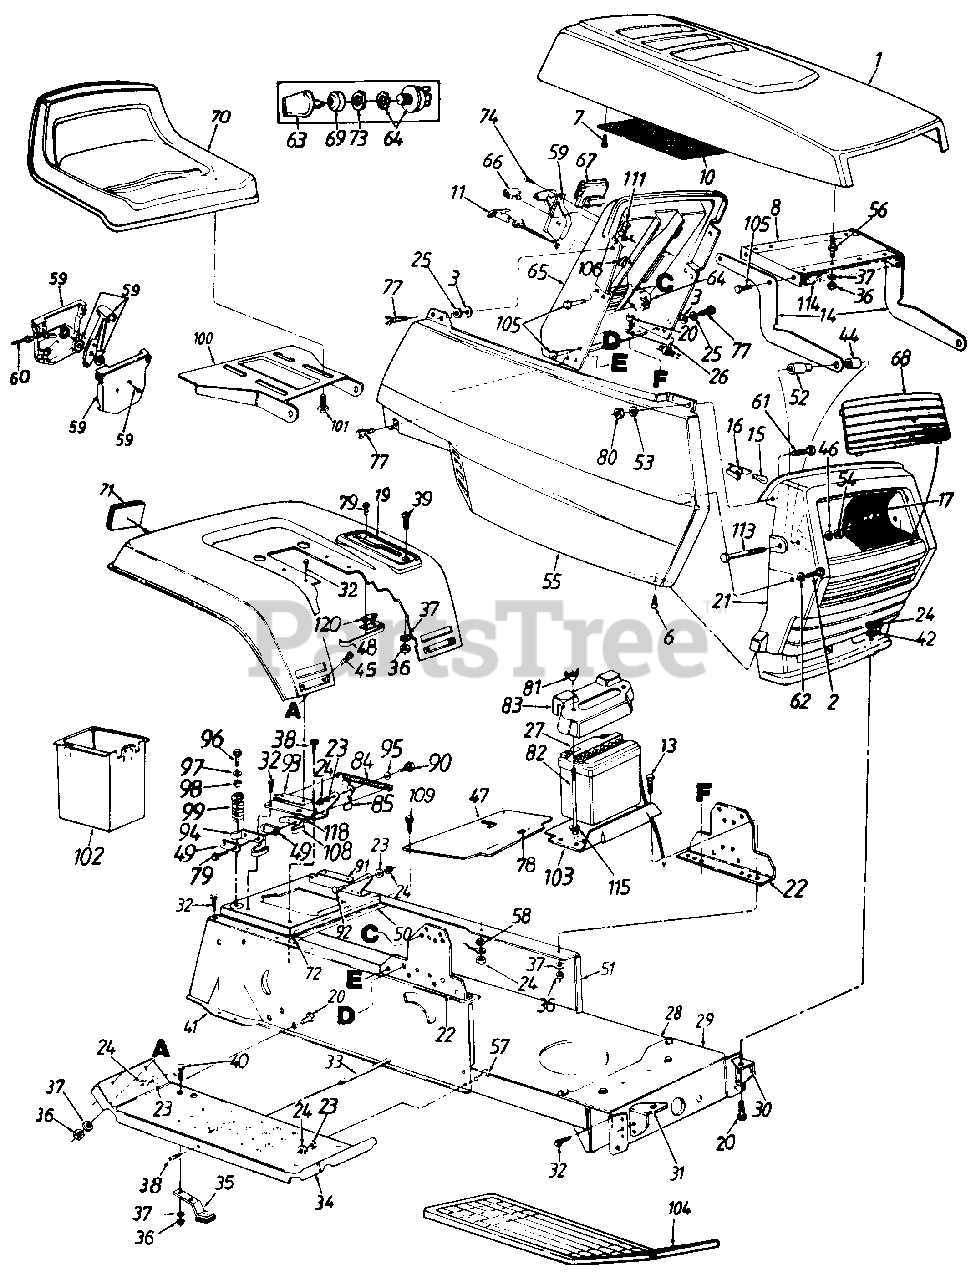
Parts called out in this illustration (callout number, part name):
3	Bolt Retainer 1/4" I.D.
6	Truss Mach. AB-Tap Scr. #10 x .5" Lg.
7	Hex Wash Hd. AB-Tap Scr. #8 x .5" Lg.
8	Hood Plate
11	Choke Control 38" Lg.
13	Hex Bolt 1/4-20 x .62" Lg.
14	Hood Hinge
15	Lamp
16	Twist Lock-Lamp Socket
17	Refiector-Headlight
19	Speed Control Index Brkt.
20	Hex Bolt 5/16-18 x .75 Lg.
21	Grille
22	Dash Support Bracket
23	L-Wash. 5/16" l.D.
24	Hex Nut 5/16-18 Thd.
25	Fl-Wash. 1/4" I.D. x .93" O.D.
26	Cable Tie
27	12 Volt Battery
28	Lower Frame
29	Front Pivot Brk't.
30	Grille Mount Brk't.-L.H.
31	Grille Mount Brk't.-R.H.
32	Hex Wash. Hd. AB-Tap Scr. 5/16 x .75 Lg.
33	Running Board Rod
34	Running Board
35	Blade Brake Ass'y.
36	Hex Nut 1/4-20 Thd.
37	L-Wash. 1/4" I.D.
38	Truss Mach. Scr. 5/16-18 x .75"
39	Truss Mach. Scr. 1/4-20 x .75
40	Carr. Bolt 1/4-20 x .62"
41	R.H. Side Frame
42	Fl-Wash. .34" l.D. x.68" O.D.
45	Carriage Bolt 1/4-20 x .50" Lg.
46	Fl-Wash. .328" l.D. x .68" O.D.
47	Transmission Panel
48	Reverse Safety Switch
49	Insulator Plate
50	Hitch Plate
51	L.H. Side Frame
52	Shld. Spacer .33" I.D.
53	Fl-Wash. .281" l.D. x .5" O.D.
54	Hex Cent. L-Nut 5/16-18 Thd.
55	Side Cover-R.H.
56	Double Ended Stud 1/4-20 Thd.
57	Hex Tap Scr. 5/16-18 x 7/8" Lg.
58	Ext. L-Wash. 5116" I.D.
59	Throttle Control Box Ass'y.
60	Throttle Control Wire 35" Lg.
61	Hex Bolt 1/4-20 x .62" Lg.
62	Fl-Wash. .281" I.D. x .73" O.D.
64	Ignition Switch
66	Light Switch
67	Ammeter
68	Lens
69	Ignition Switch Cap
71	Reflector
72	Speed Nut #10Z
73	Ignition Switch Nut
74	Truss Mach. AB-Tap Scr. #10 x ,5" Lg.
77	Hex Wash. Hd. Tap Scr. 1/4 x .75" Lg.
78	Snap Bushing
79	Hex Wash. Hd. AB-Tap Scr. #8 x ,50" Lg.
80	Hex L-Nut 1/4-20 Thd.
81	Wing Nut 1/4-20 Thd.-Plast
82	Battery Hold Down Rod
83	Battery Cover
84	Ext. Spring 6.3l" Lg.
85	Seat Lift Brkt.
90	Shld. Bolt .437" Dia. x .268n
91	Seat Pivot Brkt. Support-L.H.
92	Shld. Bolt .437" Dia. x .162"
93	Seat Pivot Brkt. Support-R.H.
94	Spring Switch
95	Spr.-Wash. ,445" l.D.
96	Hex Wash. Hd. Tap Scr. 5/16-18 x 1" Lg.
97	Fl-Wash. .344" l.D.
99	Compression Spring
100	Seat Pivot Bracket
101	Hex Tap Scr. 3/8-16 x .75"
103	Battery Bracket
104	Foot Pad-L.H.
105	Hex Tap Scr. 1/4-20 x .5" Lg.
106	Choke Retainer
108	Spring Switch
109	Truss Mach. Tap Scr. #10 x .5" Lg.
111	Speed Nut 1/4-20 Thd.
113	Hex Bolt 5/16-18 x 2.75" Lg.
115	Push Nut
118	Insulator Boss Plate
120	Insulator Nut Plate
